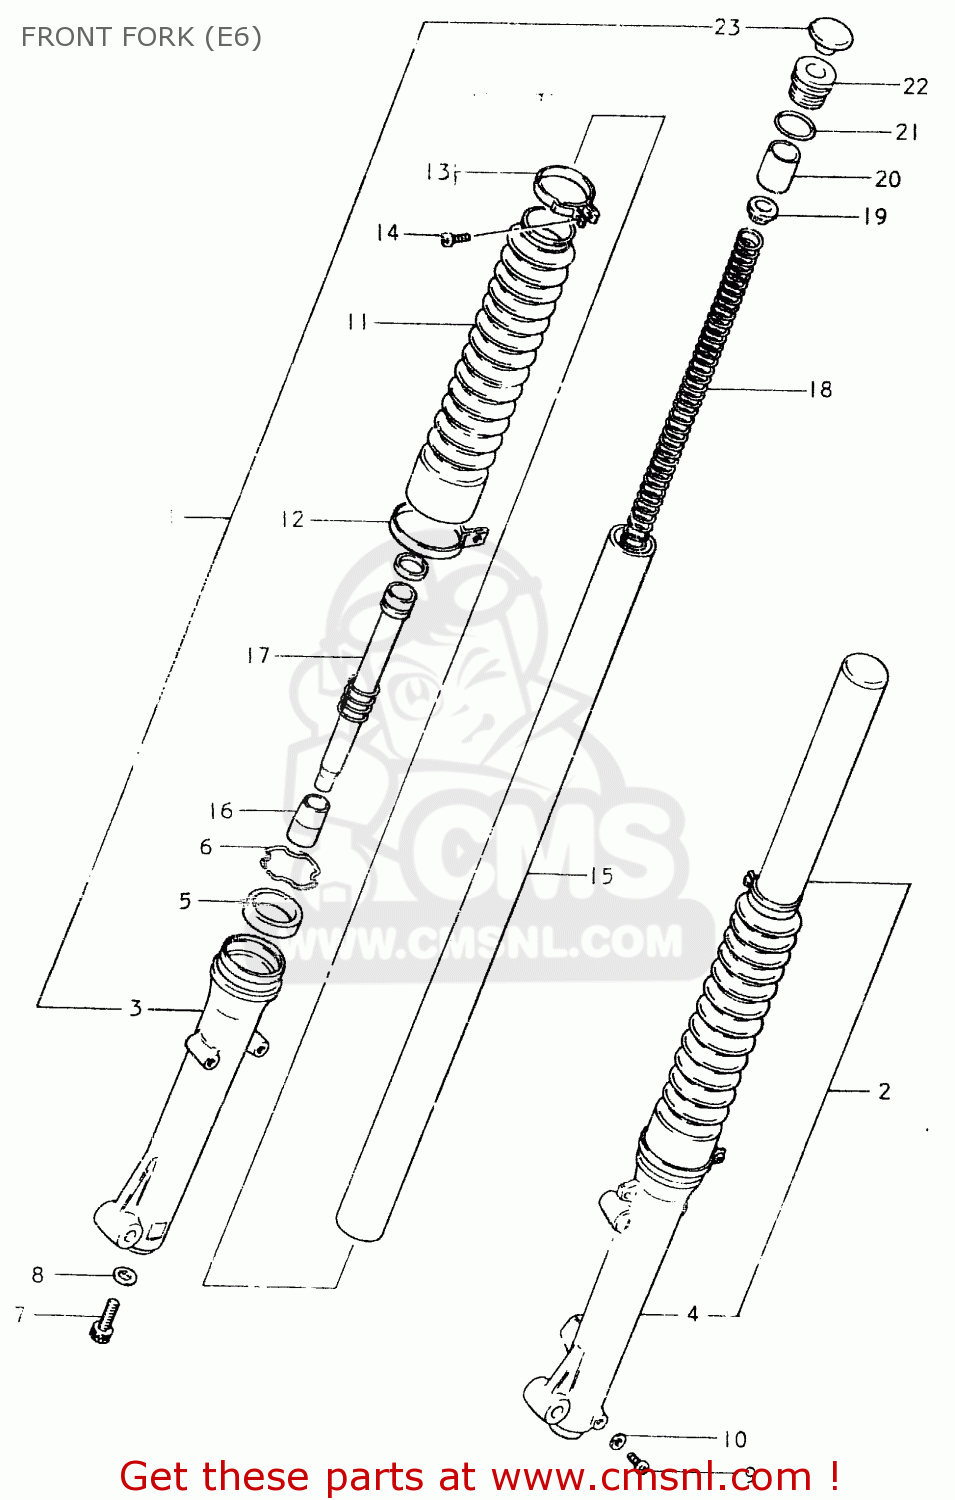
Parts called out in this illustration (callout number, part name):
1	DAMPER ASSY, RH
2	DAMPER ASSY, LH
3	TUBE,OUTER,RIGHT
4	TUBE,OUTER,LEFT
5	OIL SEAL,FRONT FORK
6	7
7	BOLT,FORK CYLINDER(10X25)
8	GASKET (NAS)
9	SCREW
10	GASKET,DRAIN,PLUG (NAS)
11	BOOT
12	BAND,FRONT FORK COVER
13	BAND,BOOT
14	SCREW
15	TUBE,FORK,INNER
16	PIECE,OIL LOCK
17	CYLINDER,FRONT FORK
18	SPRING
19	GUIDE,FRONT FORK SPRING C
20	SPACER,SPRING
21	O RING
22	CAP,FORK INNER TUBE
23	CAP,FRONT FORK
